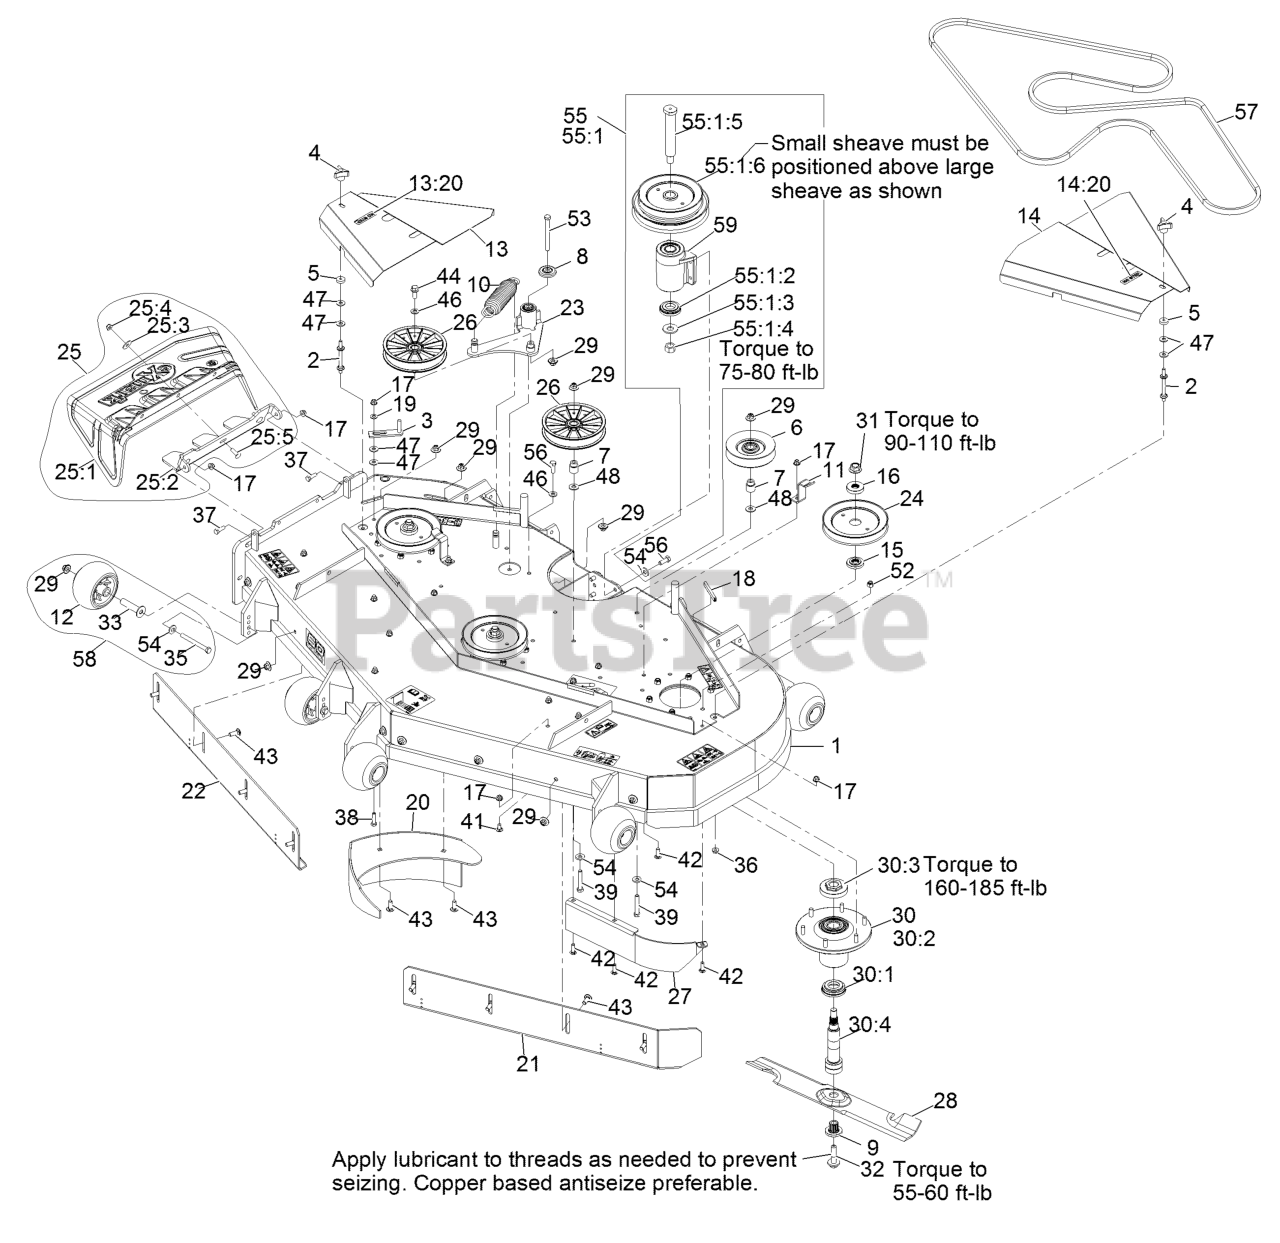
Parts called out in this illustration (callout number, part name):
1	ASM, DECK 605 W/DECALS
2	STUD-SHIELD, BELT (SHORT)
3	GUIDE-BELT
4	KNOB-3 PRONG
6	PULLEY-IDLER
7	BUSHING-IDLER
8	GUARD-TOP
9	BUSHING,SPLINED
10	SPRING-EXTENSION
11	LATCH,BELT SHIELD
12	ROLLER-SCALP, ANTI
13	SHIELD, BELT RH 605 W/DEC
13:20	DECAL,NO STEP
14	SHIELD, BELT LH 605 W/DEC
14:20	DECAL,NO STEP
15	SPACER,SPLINED STEPPED
16	SPACER,SPLINED
17	NUT-HF, NI
18	STRIP-SEAL
19	WASHER-SPRING
20	WLD,DOGLEG 605
21	WLD,BAFFLE FRT ADJ LH 605
22	WLD,BAFFLE FRT ADJ RH 605
23	KIT, IDLER ARM W/BEARINGS
24	SHEAVE, BLADE DRIVE 6.13
25	ASM, DISCHARGE CHUTE
25:1	CHUTE,DISCHARGE LZ
25:2	HINGE,DISCHARGE CHUTE
25:3	WASHER-FLAT
25:4	NUT-HF, NI
25:5	SCREW-CARR
26	PULLEY,IDLER 6"
27	BAFFLE,SCROLL 605
28	Blade-Extreme 2, 20.75
28	Blade-High Lift Solid, 20.75
28	Blade,High Lift Notched 20.75
29	Nut-Nyloc 3/8-16 Flg
30	ASM,SPINDLE HOUSING
30:1	GUARD,BOTTOM
30:2	ASM,CUTTER HOUSING
30:3	NUT, SPINDLE 7/8-14
30:4	SPINDLE,DOUBLE SPLINE
31	NUT-FLANGE, CENTERLOCK
32	SCREW,SEMS 1/2-20 X 2.19
33	AXLE, ROLLER
35	SCREW-HH 3/8-16 X 3 3/4 GR 8
37	SCREW-HH
38	SCREW-HH
39	SCREW-HH
41	SCREW-CARR
42	SCREW-CARR
43	SCREW-CARR
44	SCREW-HHF
46	WASHER-FLAT
47	WASHER-FLAT
48	WASHER-FLAT
52	NUT-LOCK, NI
53	SCREW-HH
54	WASHER-BELLEVILLE
55	KIT,JACKSHAFT 60/72-3750
55:1:2	SPACER-GUARD, BOTTOM
55:1:3	WASHER-SPRING
55:1:4	NUT-HEX
55:1:5	JACKSHAFT
55:1:6	SHEAVE, JACKSHAFT DOUBLE
56	SCREW-HH
57	BELT,BLADE DRIVE
58	KIT, ANTI-SCALP ROLLER
59	KIT, JACKSHAFT ASSY
